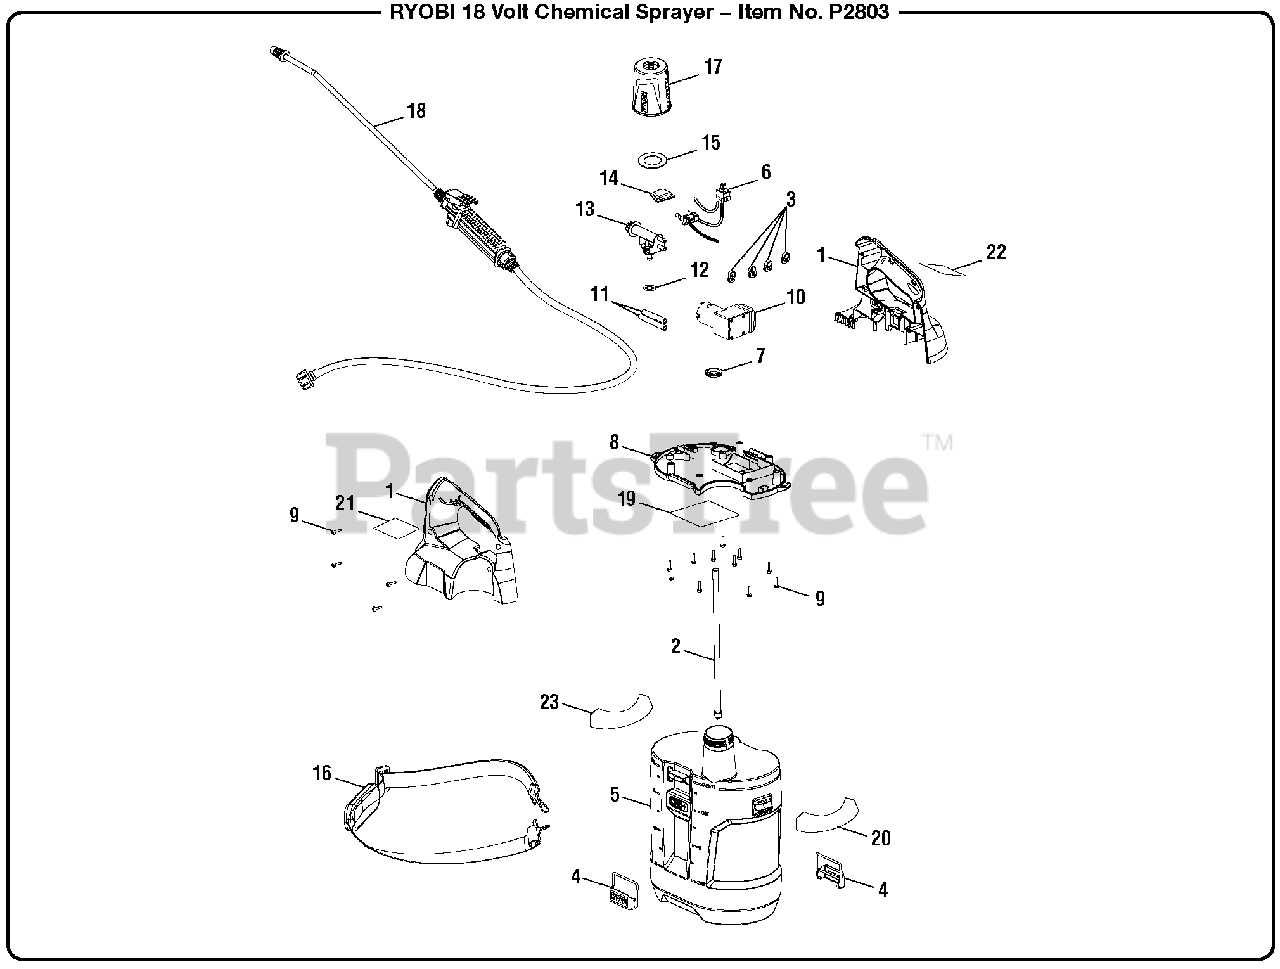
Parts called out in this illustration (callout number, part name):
1	Handle Housing Assembly
2	Tube (Long)
3	Hose Clip
5	Water Tank Assembly
6	Wiring Harness and Switch Assembly
7	Rubber Seal
8	Housing Deck Assembly
9	Screw (M4x14 mm)
10	Pump Diaphragm Assembly
11	Tube (Short)
13	Connector
14	Switch Cover
15	Rubber Seal
16	Shoulder Strap
17	Tank Cap Assembly
18	Trigger Handle Assembly
19	Data Label
20	Warning Icon Label
21	Notice Label (A)
22	Notice Label (B)
23	Logo Label
